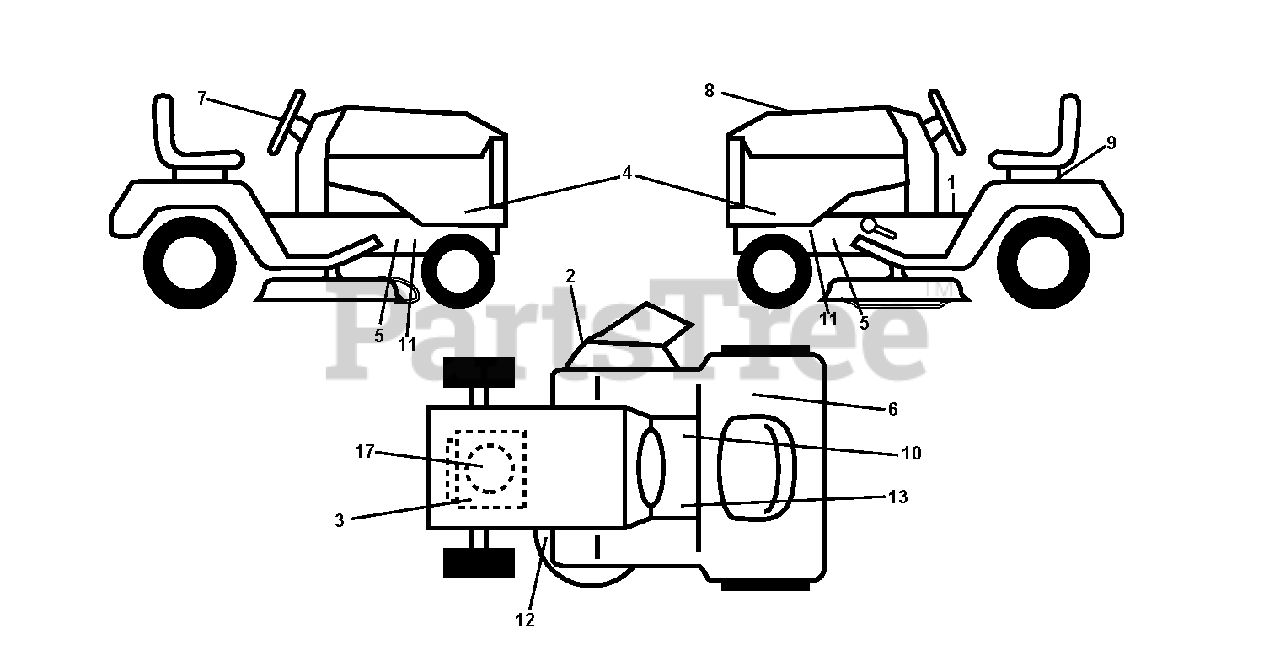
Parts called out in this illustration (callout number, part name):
2	DECAL, WARN. DEFLECT/CTFGR
9	DECAL BTRY SYMBOLS
10	DECAL PARK BRAKE
